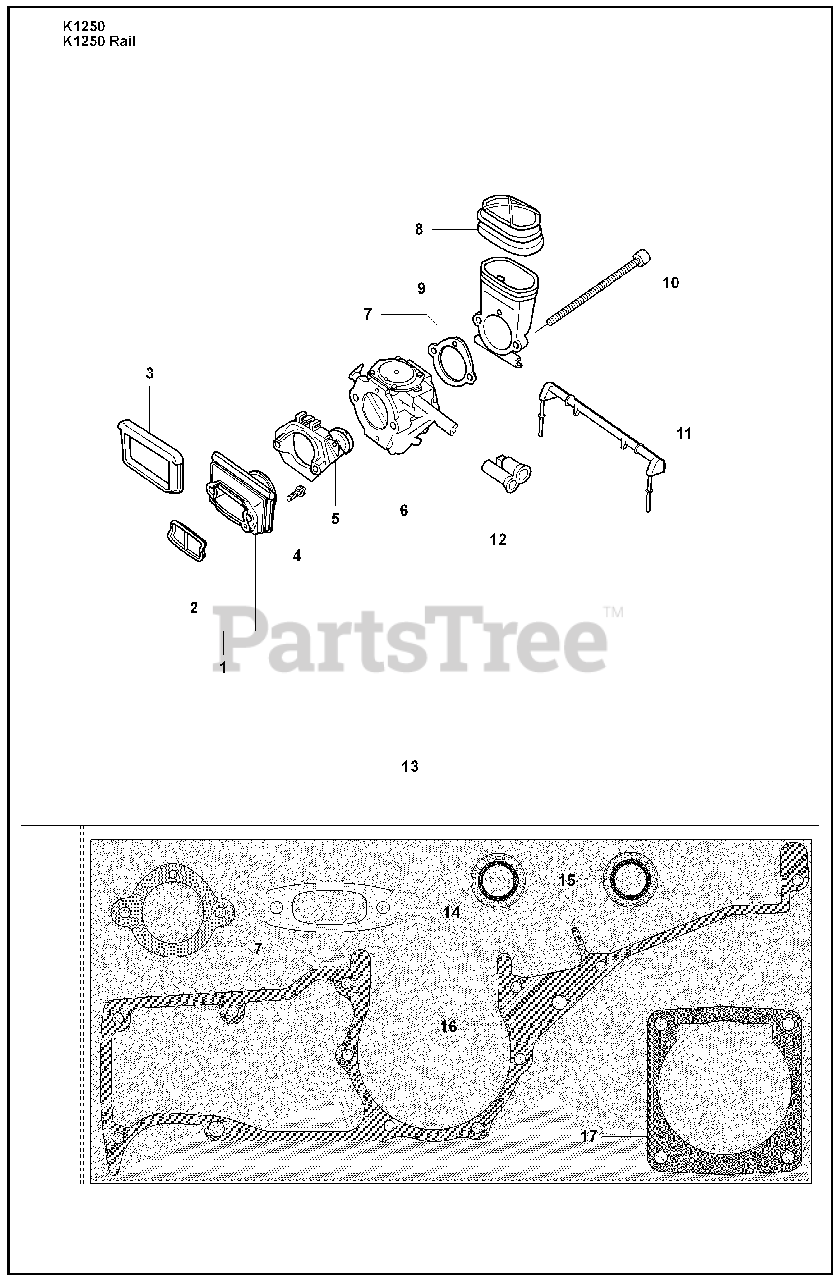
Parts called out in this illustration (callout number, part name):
1	INLET PIPE
6	CARBURETTOR
7	GASKET
9	INLET BEND
12	CHISEL GUIDE
13	GASKET KIT
14	GASKET MUFFLER
15	SEALING RING
16	CRANKCASE GASKET
